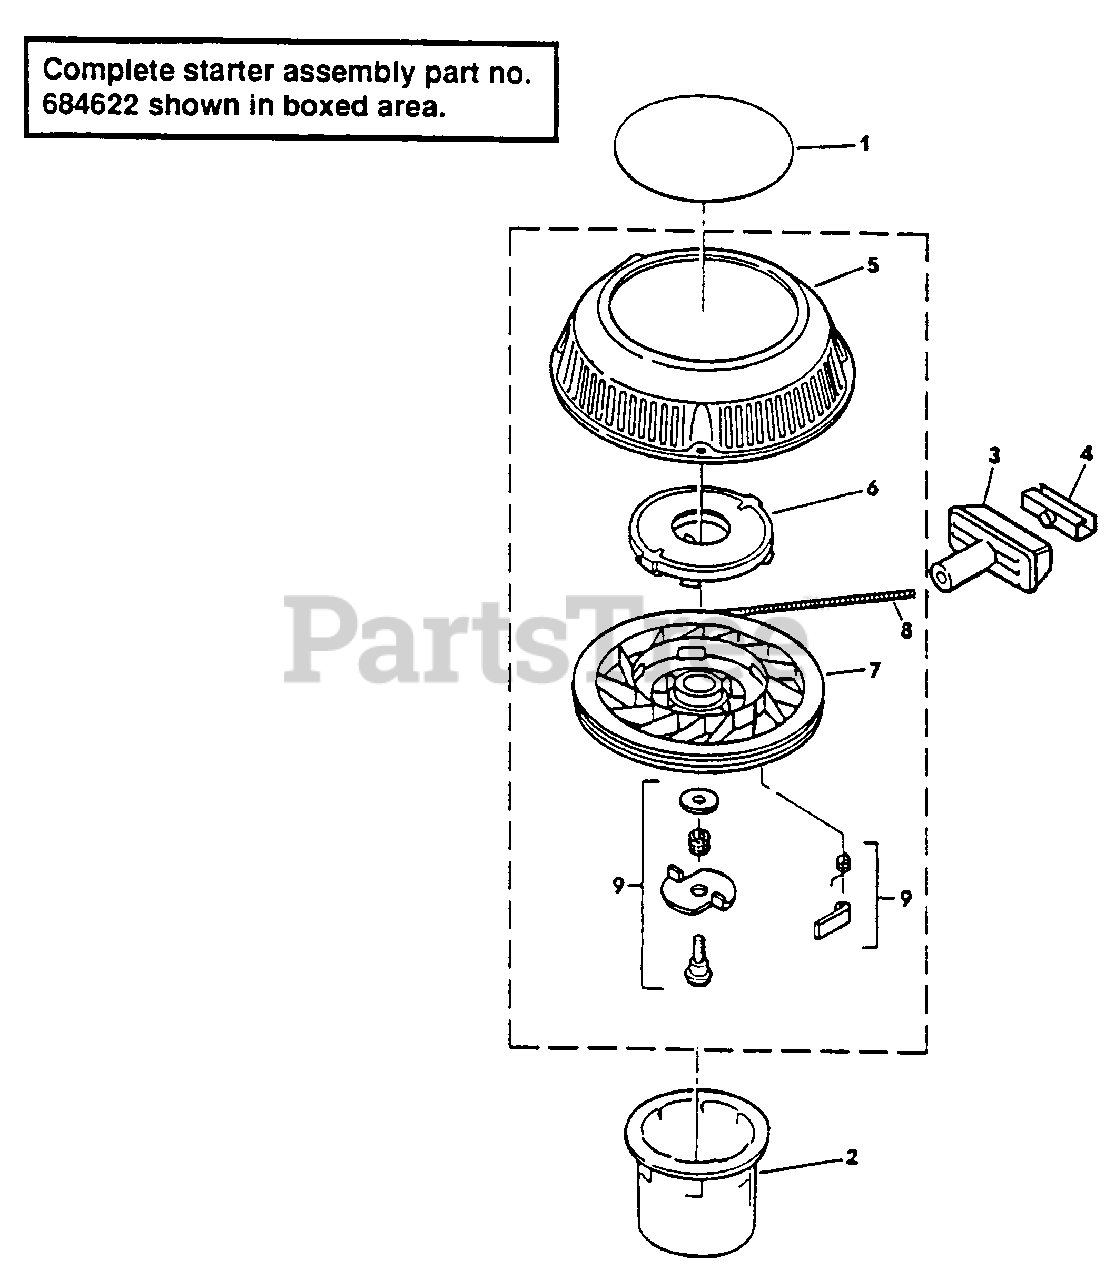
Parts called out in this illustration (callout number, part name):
1	Decal
2	Starter Hub
3	Starter Handle
4	Clip-Rope Insert
5	Starter Housing & Shaft
6	Recoil Spring & Keeper
7	Pulley
8	Rope
9	Dog Kit Assembly
